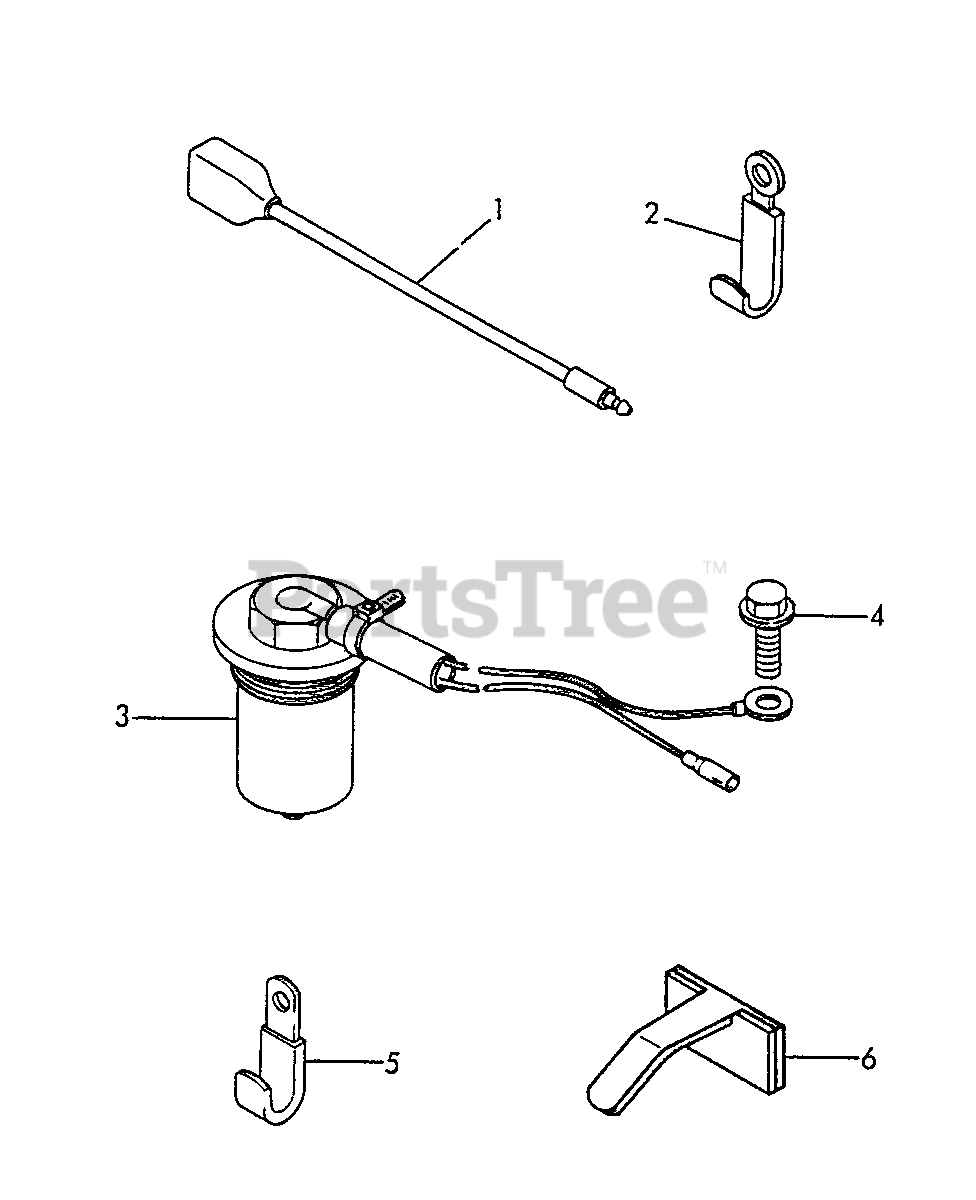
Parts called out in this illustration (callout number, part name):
2	CLAMP
3	SENSOR, OIL LEVEL
4	BOLT - 6×12
5	CLAMP
6	CLAMP
